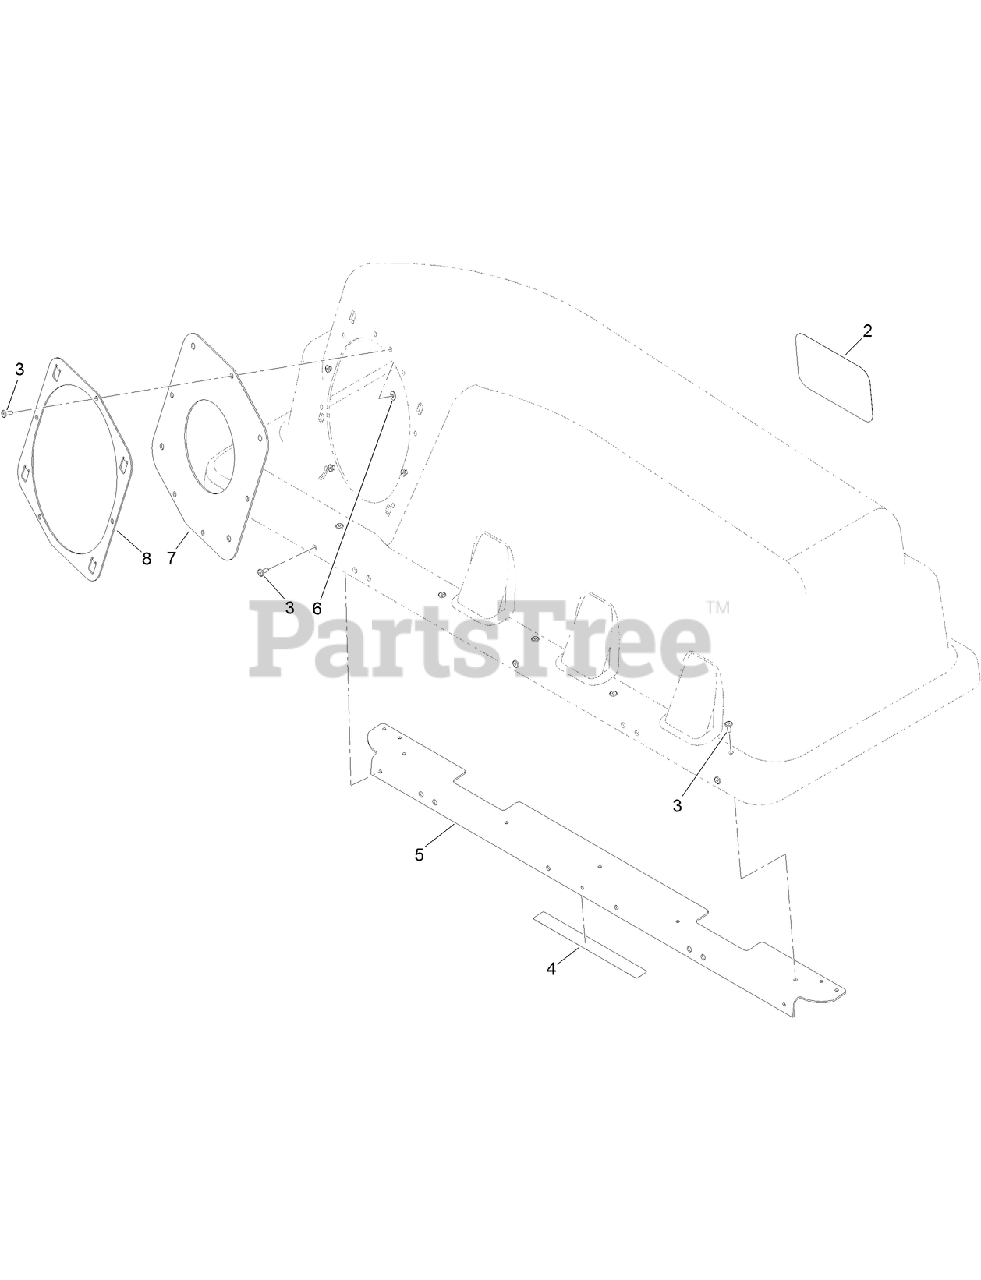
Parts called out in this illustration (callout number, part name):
2	DECAL
3	RIVET-BLIND
4	DECAL-CAUTION, BAGGER
5	STIFFENER-BAGGER, TOP
6	WASHER-FLAT
7	GASKET
8	RING-RETAINER
